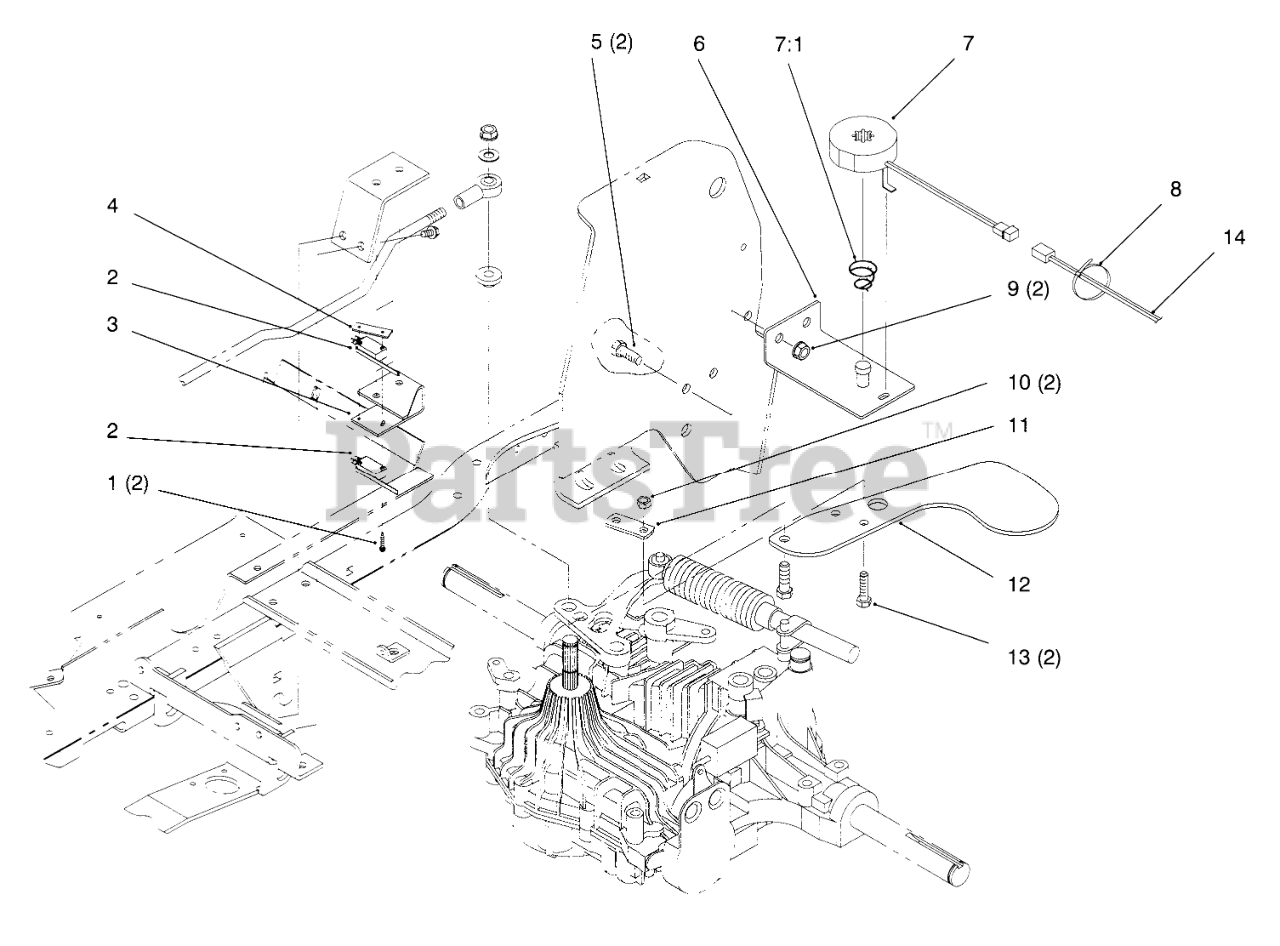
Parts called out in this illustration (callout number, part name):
1	SCREW-HH
2	SWITCH-MICRO
3	BRKT - BRAKE SWITCH
4	NUT-SPEED
5	SCREW-HH
6	Cruise Bracket
7	Magnet Assembly (INCL 7:1)
7:1	SPRING-COMPRESSION
8	TIE-CABLE
9	NUT-LOCK, NI
10	NUT-LOCK, NI
11	CLAMP - CRUISE
12	ARM - CRUISE
13	SCREW-HH
14	HARNESS - WIRE
